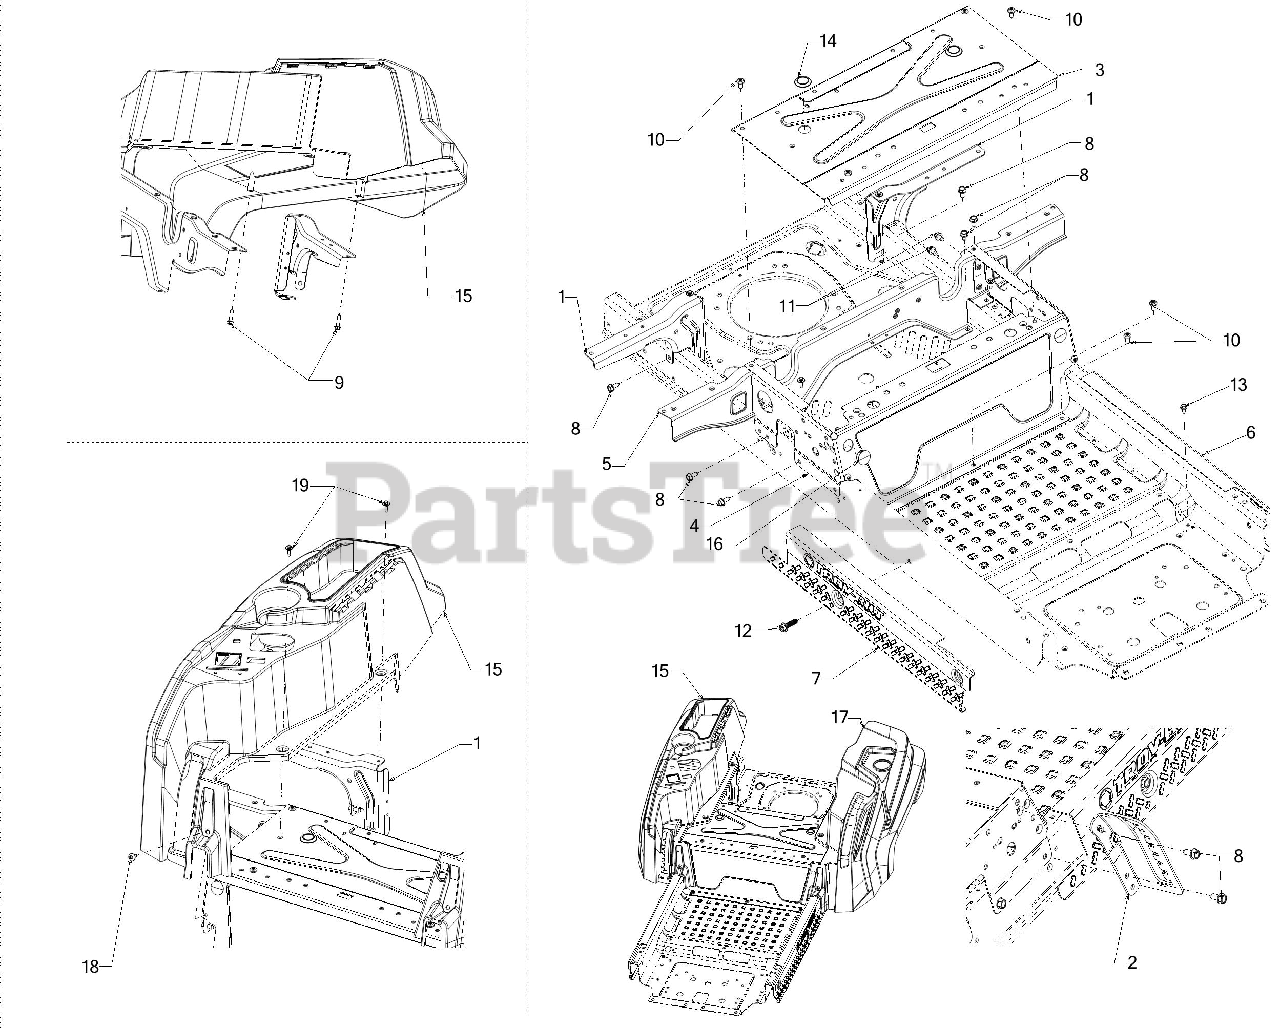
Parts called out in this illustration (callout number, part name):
1	REAR TANK BRACKET
2	HEIGHT INDEX BRACKET
3	SEATBOX TOP PLATE
4	SEAT FRAME
5	REAR SEATBOX BRACE
6	FRAME SUPPORT (LH)
7	FRAME SUPPORT (RH)
8	SCREW 5/16-18 x .750
9	SCREW 5/16-14 x 1
10	SCREW 5/16-18 x .750
11	SCREW 5/16-18 x .500
12	SCREW 3/8-16 X1.250
13	SCREW 1/4-20X.625
15	CONSOLE (RH)
16	PLASTIC PLUG
17	CONSOLE (LH)
18	TORX SHOULDER SCREW 1/4-20
19	SHOULDER SCREW M6-1 .368 X.115
